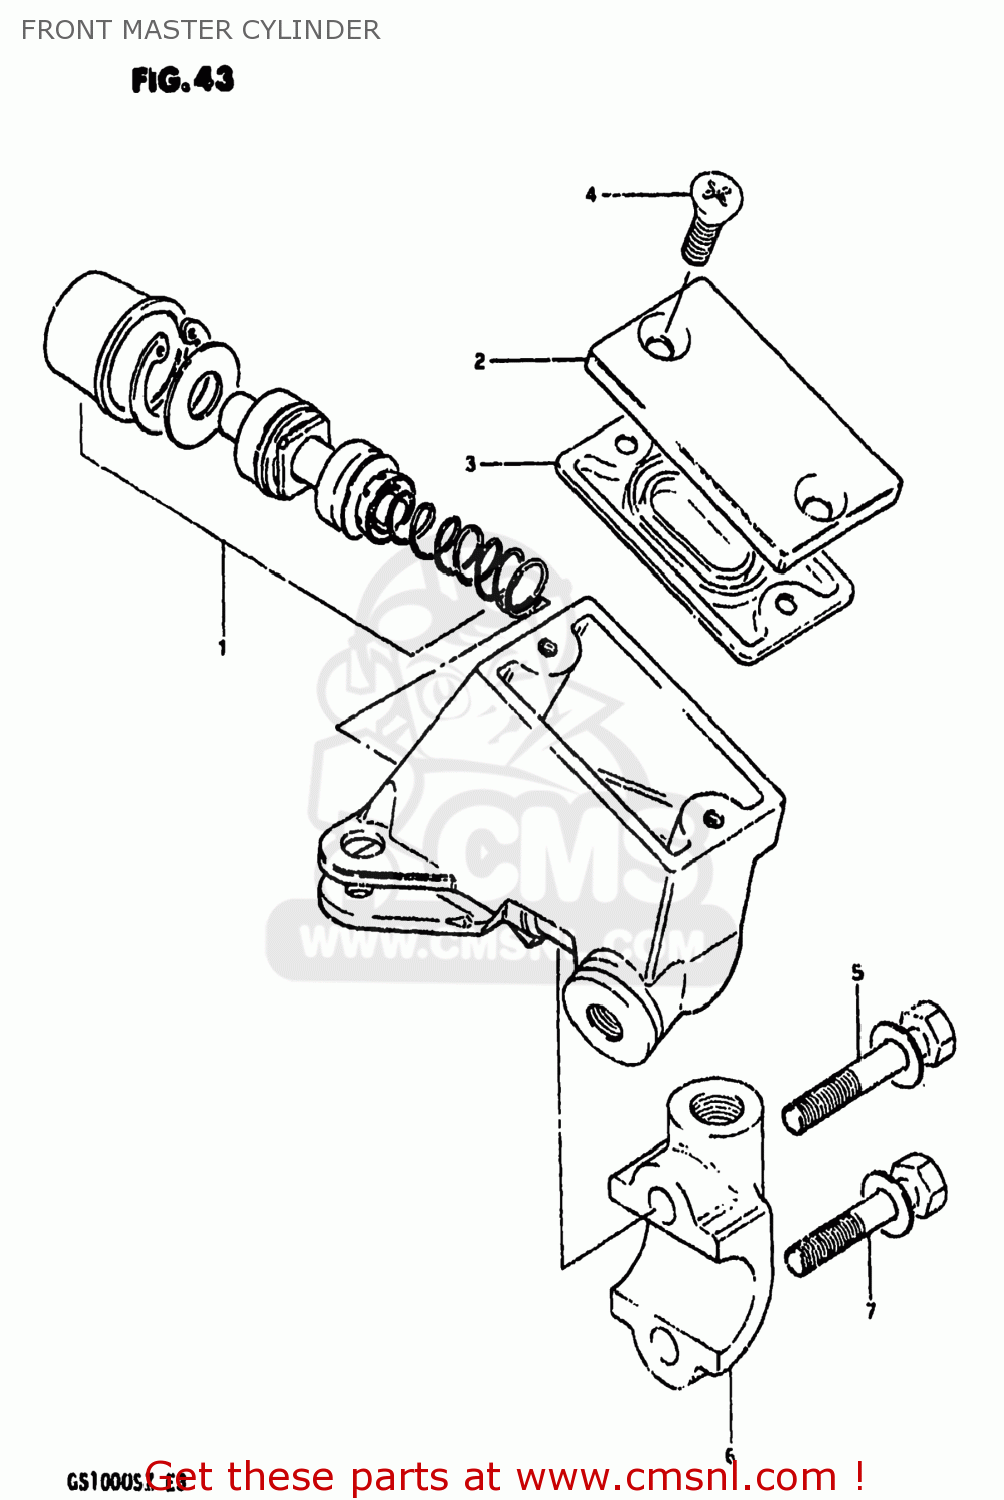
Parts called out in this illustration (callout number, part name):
1	PISTON & CUP SET
2	CAP,MASTER CYLINDER,REAR
3	DIAPHRAGM,MASTER CYLINDER
4	SCREW,RESERVOIR CAP
5	BOLT,MASTER CYLINDER H
6	HOLDER
7	BOLT,MASTER CYLINDER H
